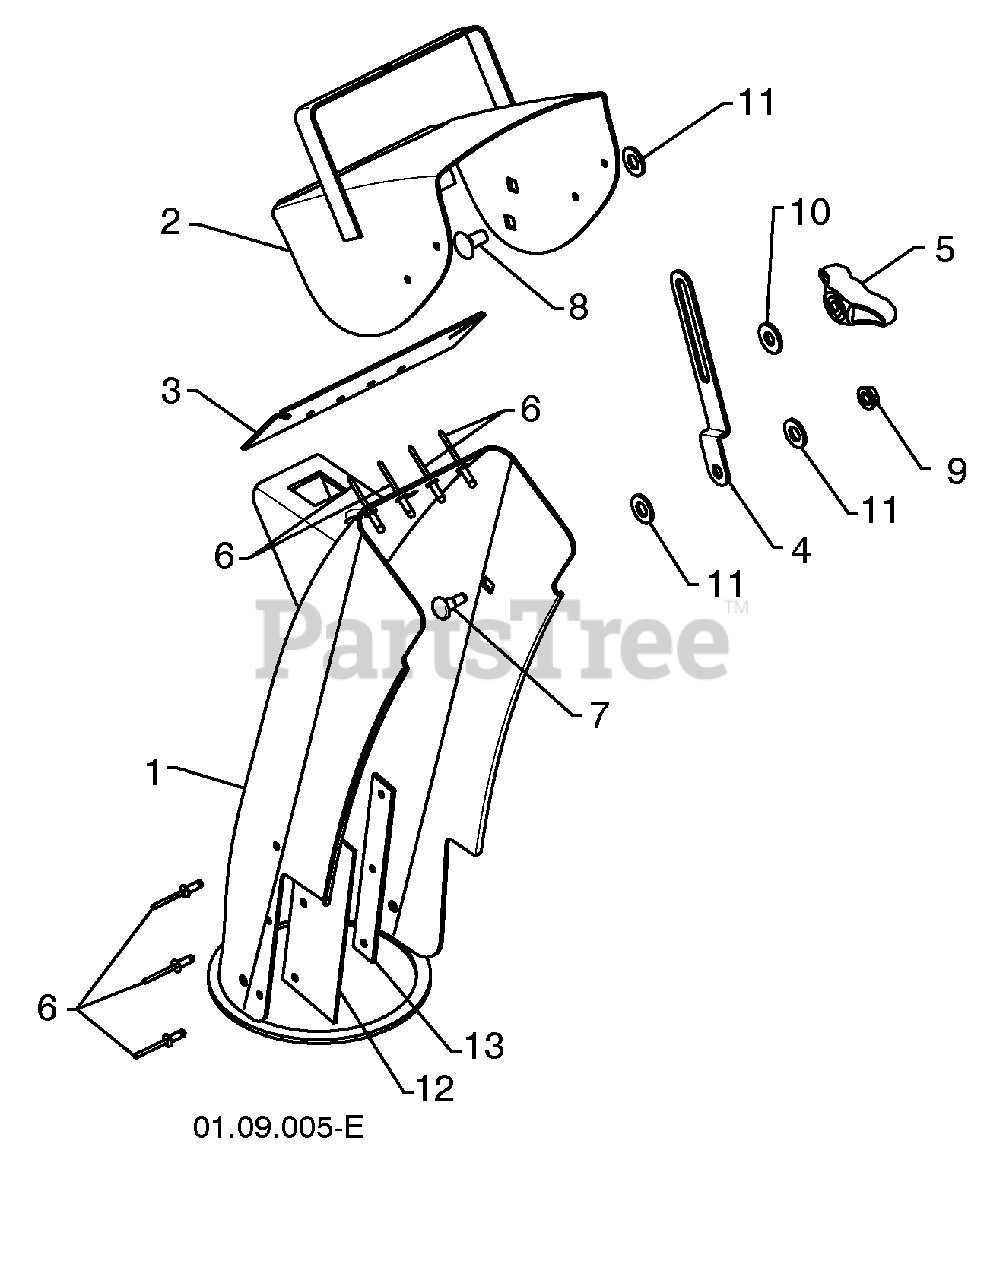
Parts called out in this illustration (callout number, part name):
1	CHUTE WELDMENT
2	DEFLECTOR WELDMENT
3	DEFLECTOR SEAL
5	KNOB BLACK
6	POP RIVET
7	SHOULDER BOLT 1/4-20 X .704
8	CARRIAGE BOLT 5/16-18 X .625
9	NUT 1/4-20
10	WASHER
11	PLASTIC WASHER
12	CHUTE SNOW SHIELD
13	SHIELD RETAINER STRAP
